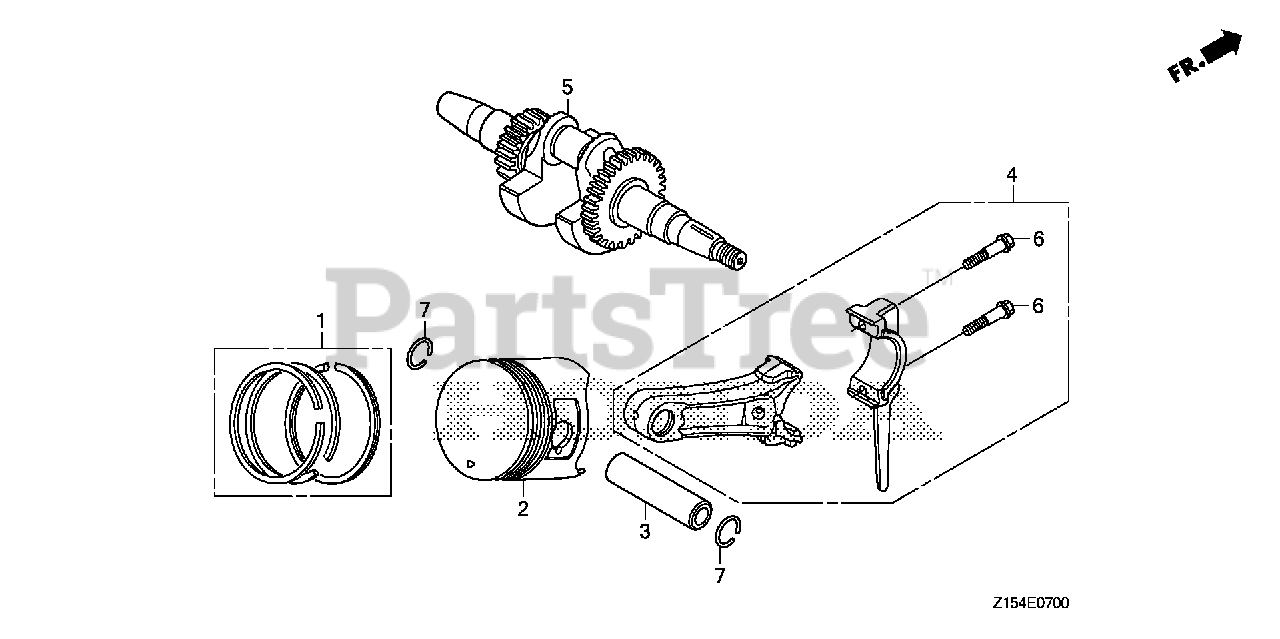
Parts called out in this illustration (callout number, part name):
1	RING SET, PISTON (STD) (FUJIAN DONGYA MACHINERY)
1	RING SET, PISTON (STD) (TPR)
1	RING SET, PISTON (STD) (RIKEN)
1	RING SET, PISTON (0.25) (TPR)
1	RING SET, PISTON (0.25) (RIKEN)
1	RING SET, PISTON (0.50) (TPR)
1	RING SET, PISTON (0.50) (RIKEN)
1	RING SET, PISTON (0.75) (TPR)
1	RING SET, PISTON (0.75) (RIKEN)
2	PISTON (STD)
2	PISTON (STD) (JIALING-HONDA)
2	PISTON (0.25)
2	PISTON (0.50)
2	PISTON (0.75)
3	PIN, PISTON
4	ROD ASSY., CONNECTING (TH)
5	CRANKSHAFT
6	BOLT, CONNECTING ROD
7	CLIP, PISTON PIN (18MM)
